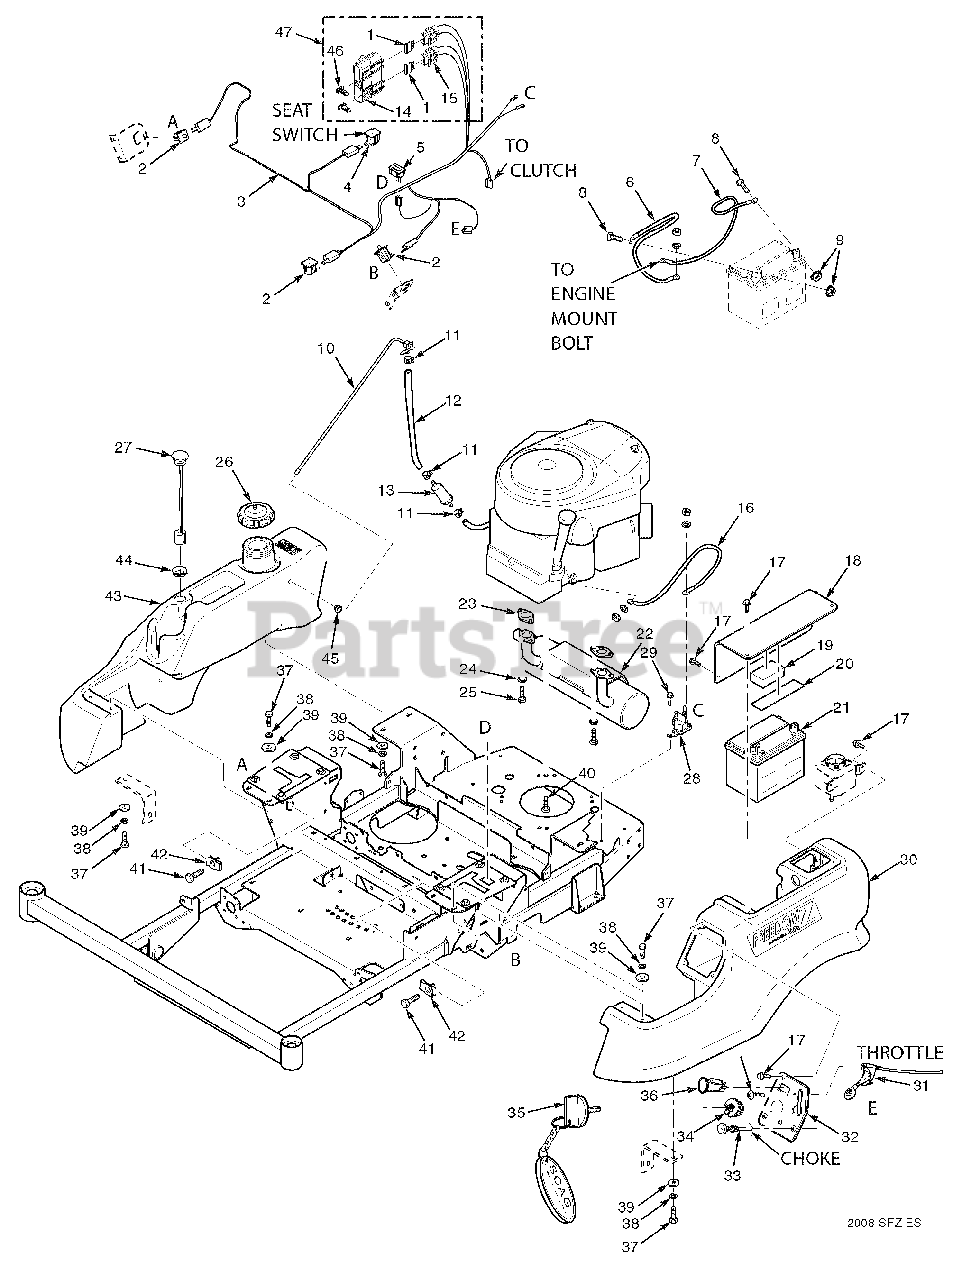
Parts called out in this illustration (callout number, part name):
1	Fuse, 20amp
2	Switch
3	Wire Harness, Main
4	Switch, Seat
5	Hourmeter
6	Battery Cable, Red 25"
7	Battery Cable, Black 27"
8	Bolt, Hex Head 1/4-20 x 1/2"
9	Nut, 1/4-20
10	Fuel Tube Assy.
11	Clamp, Fuel Hose 1/4"ID
12	Fuel Hose , 1/4" ID Non-Perm.
13	Fuel Filter
14	Cover, Sealed Double
15	Fuse Holder
16	Battery Cable, Red 9"
17	Bolt, Hex Head 1/4-20 x 1/2" Serrated Flange
18	Battery Cover
19	Pad, Battery Hold Down
20	Rubber Pad
21	Battery
22	Muffler, Briggs & Stratton
23	Exhaust Gasket
24	Lockwasher
25	Bolt
26	Cap, Fuel Tank
27	Fuel Gauge Assy.
28	Solenoid
29	Bolt, Self Tapping 1/4-20 x 3/4" Shakeproof
30	Tank, LH
31	Throttle Cable
32	Instrument Panel w/Decal
33	Choke Cable
34	Ignition Switch
35	Key, Ignition
36	PTO Switch
37	Bolt, Hex Head 5/16-18 x 3/4"
38	Lockwasher, 5/16" Spring
39	Flatwasher, 5/16-.375 x .875 x .083
40	Bolt, Hex Head 5/16-18 x 1-1/2"
41	Bolt, Hex Head 3/8-16 x 1-1/4" Special Lock
42	U-Nut, 3/8-16
43	Fuel Tank Assy, RH
44	Grommet
45	Bushing, .56" Dia. Viton
46	Clip, Wire
47	Double Fuse Assy.
